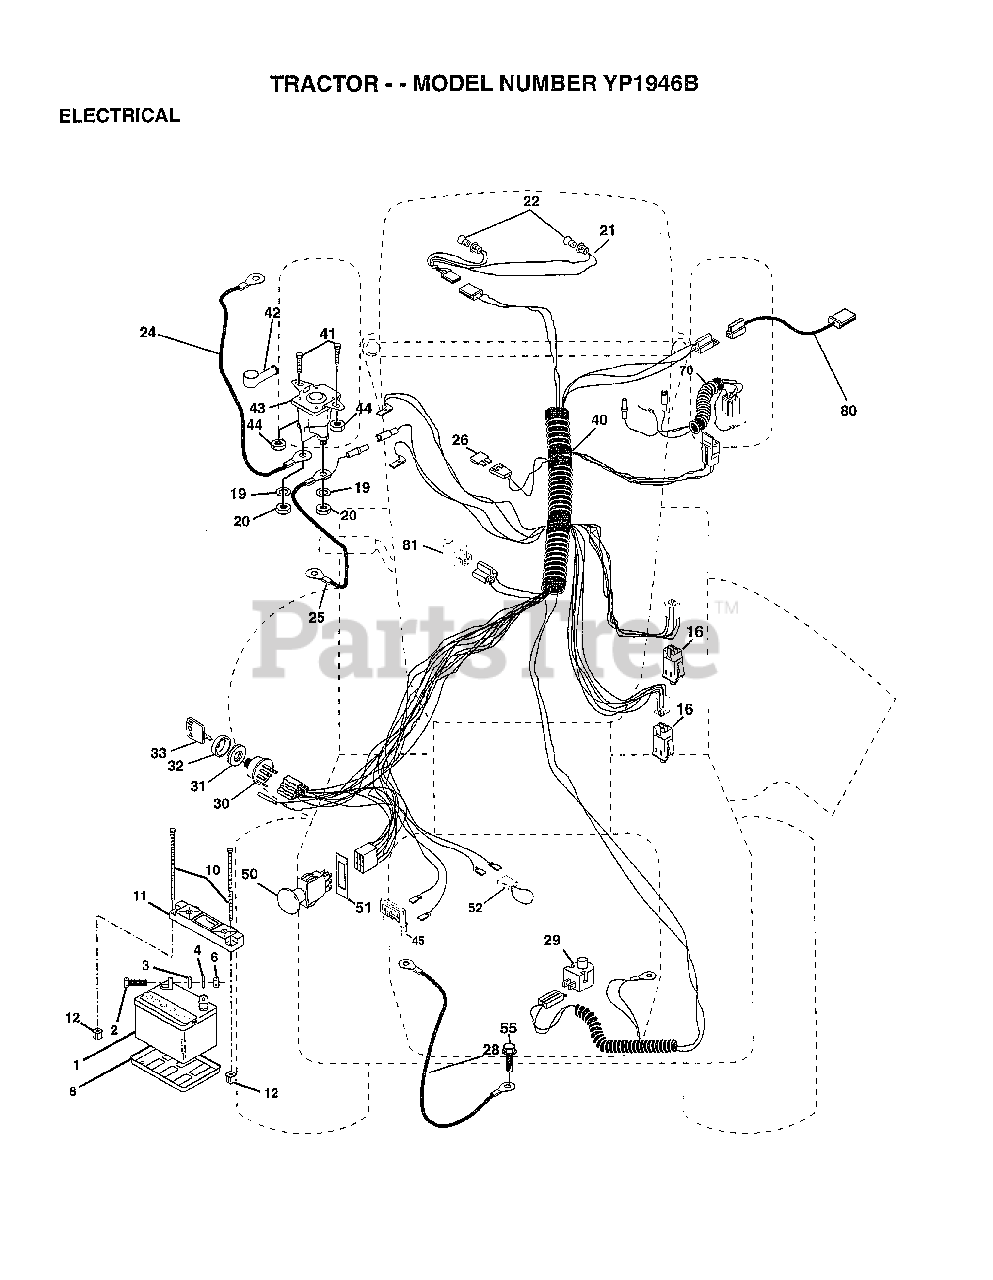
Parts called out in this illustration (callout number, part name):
3	WASHER
4	LOCKWASHER
8	"TRAY T, BATTERY"
11	HOLDDOWN BATTERY
16	SWITCH INTERLOCK
20	NUT
21	"HARNESS,LIGHT SOC"
22	HEADLAMP BULB
24	"CABLE T, BATTERY"
25	CABLE.6GA.22W/16W
26	FUSE HYT
28	CABLE.GRND.6GA.21
29	SWITCH.PLUNGER
30	SWITCH IGN 4POS
31	NUT IGNITION
32	COVER KEY SWITCH
33	KEY
40	IGNITION HARNESS
41	BOLT HXHD FIN
44	NUT HXKEP 1/4X20
45	AMMETER
50	PTO SWITCH.BLK
51	RING RETAIN PTO
52	PROTECTION LOOP
70	HARNESS ENG B&S
80	HARNESS.CLUT.EVX.
81	RELAY ASSY T
